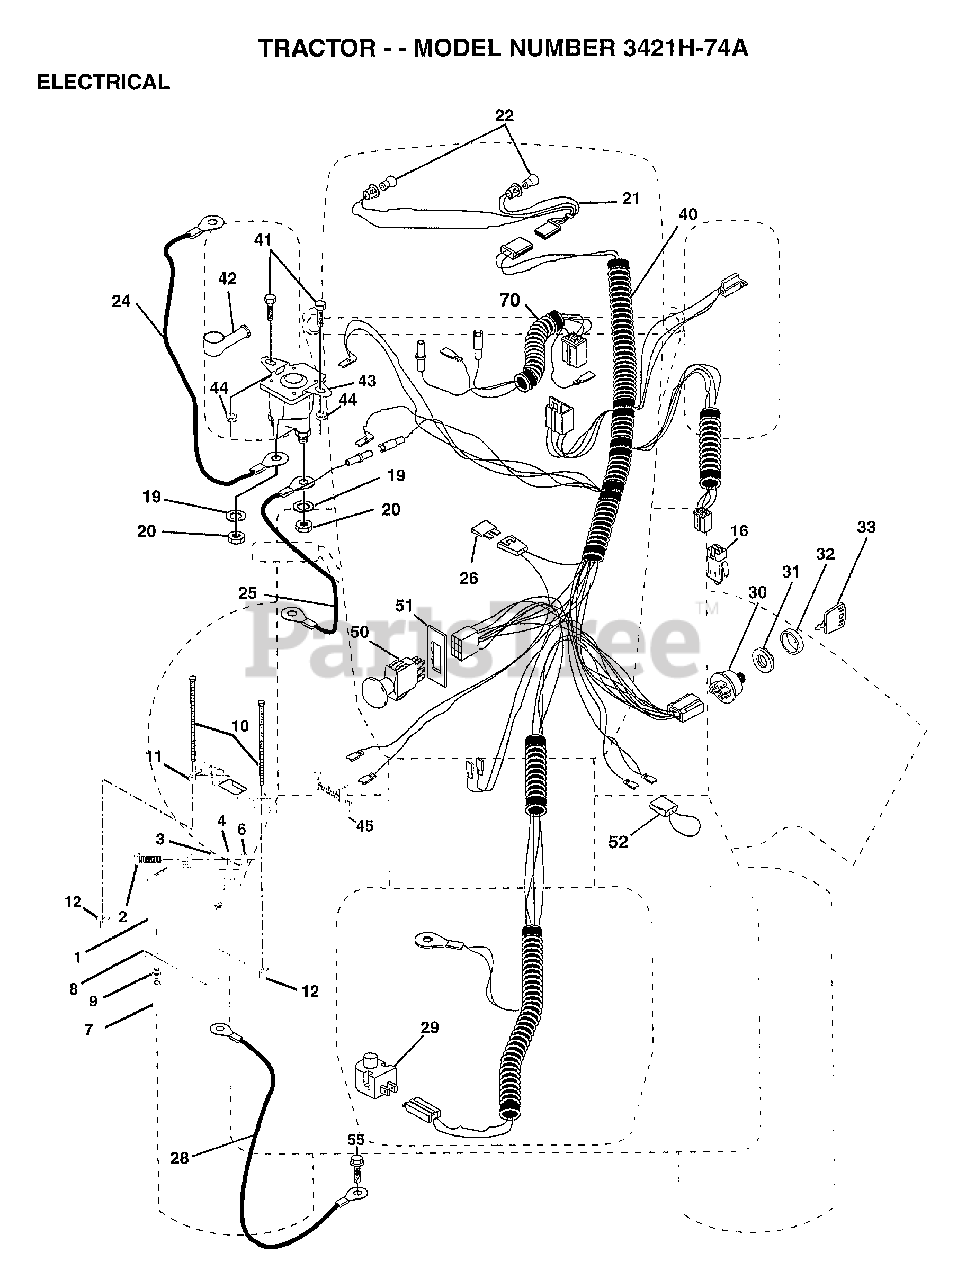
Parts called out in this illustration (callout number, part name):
2	BOLT LT
3	WASHER
4	LOCKWASHER
7	"DRAIN TU T, BATT"
8	"TRAY T, BATTERY"
9	HOSE CLAMP T
11	HOLDDOWN BATTERY
16	SWITCH INTERLOCK
20	NUT
21	"HARNESS,LIGHT SOC"
22	HEADLAMP BULB
24	CABLE.6GA.22W/16W
25	"CABLE T, BATTERY"
26	FUSE HYT
28	CABLE.GRND.6GA.21
29	SWITCH SEAT
30	SWITCH IGN 4POS
31	NUT IGNITION
32	COVER KEY SWITCH
33	KEY
40	HARNESS IGNITION
41	BOLT HXHD FIN
44	NUT HXKEP 1/4X20
45	AMMETER
50	PTO SWITCH.BLK
51	RING RETAIN PTO
52	PROTECTION LOOP
55	SCREW LT
70	HARNESS ENG B&S
